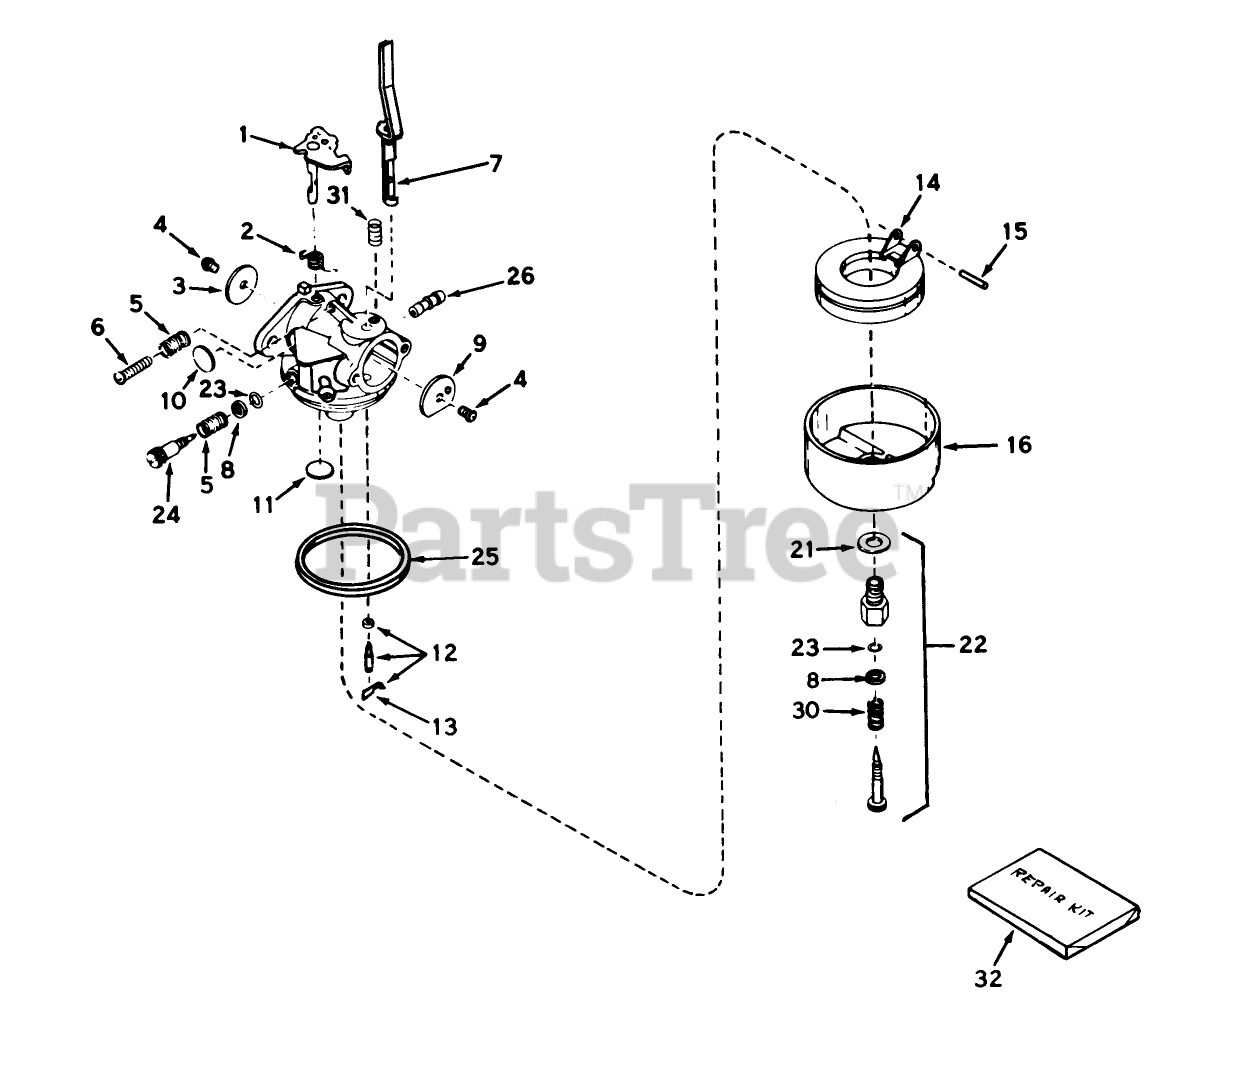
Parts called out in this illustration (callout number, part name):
1	Shaft/Lever-Throttle
2	Spring, Return
3	Shutter-Throttle
4	Screw-Shutter
5	Spring-Tension
6	Screw-Throttle Crack Screw / Idle Speed
7	Shaft Lever Assy., Choke
8	Washer
9	Shutter-choke
10	Plug-Welch, Idle Mixture Well
11	Plug-Welch, Atmospheric Vent
12	Inlet Needle, Seat Clip Assy. (Incl. No. 13)
13	Clip-Spring
14	Float
15	Shaft-Float
16	Bowl-Float (no drain)
21	Washer-Bowl Nut
22	Adjustment Screw Assy., Main (Incl. Nos. 5A, 21 23)
23	ORing
24	Screw, Idle Adj.
25	O Ring-Bowl, Float
26	Fuel Fitting
30	Spring
31	Spring-Positioning, Choke
32	Repair Kit (Incl. items marked *)
